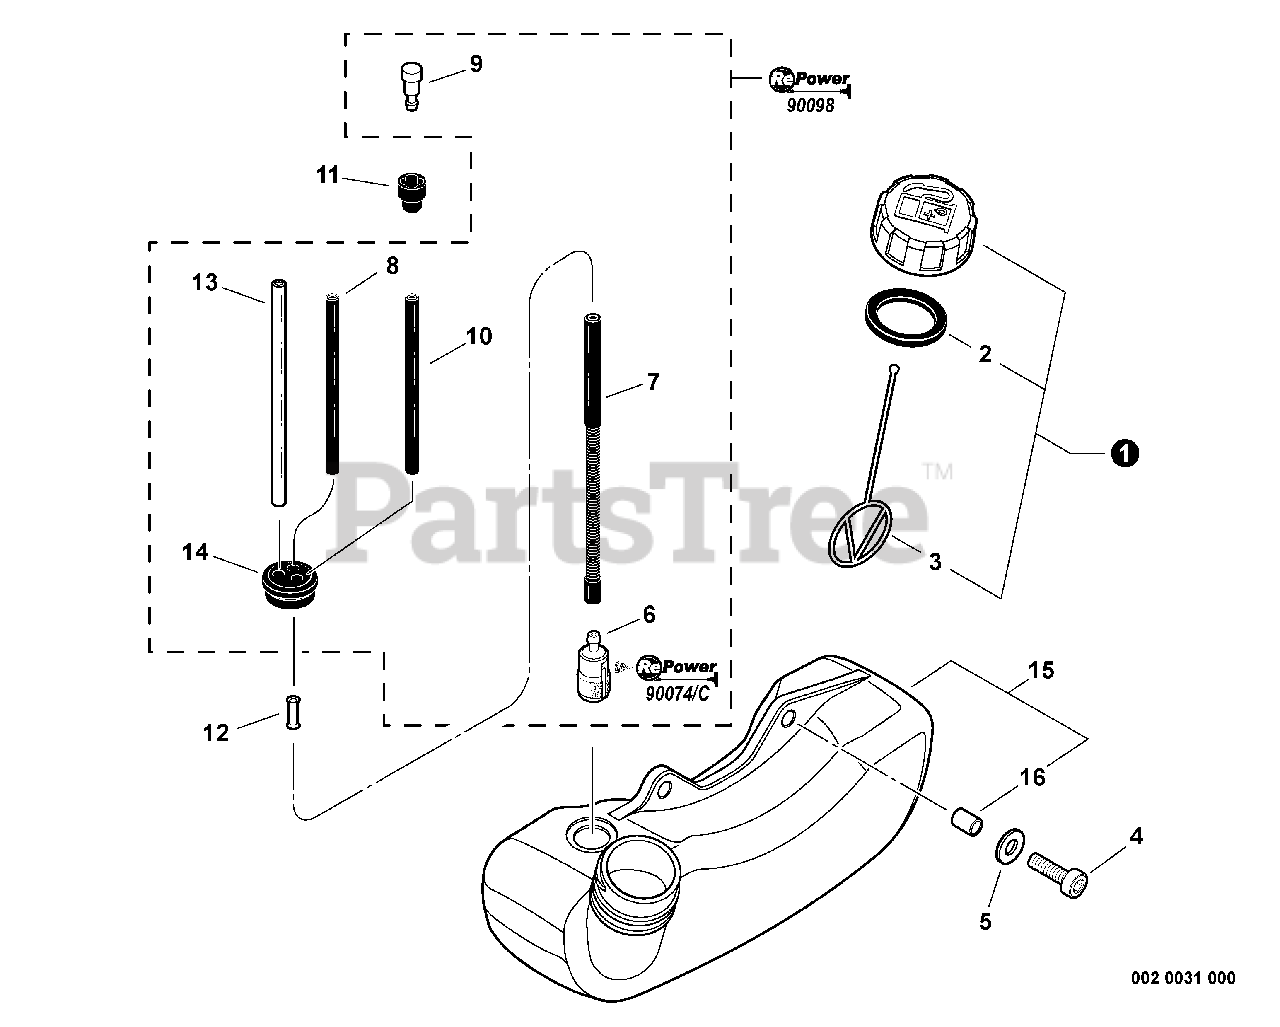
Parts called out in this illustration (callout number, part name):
1	CAP ASSY, FUEL
2	GASKET, FUEL CAP
3	CONNECTOR, CAP L= 100 MM
4	BOLT 5×16
5	WASHER 5.5×12×0.8
6	FILTER, FUEL
7	PIPE, FUEL 3×7×100 FLEXIBLE
8	PIPE, FUEL 3×5×90 BLACK
9	VENT ASSY
10	PIPE, FUEL 3x-5x-70 BLACK
11	HOLDER, VENT
12	CONNECTOR, PIPE
13	PIPE, FUEL RETURN 3×6×90 MM CLEAR
14	GROMMET, FUEL
15	TANK ASSY, FUEL
16	SPACER 6.2×7.8×6
17	FUEL SYSTEM KIT
18	TUNE-UP KIT - REPOWER
